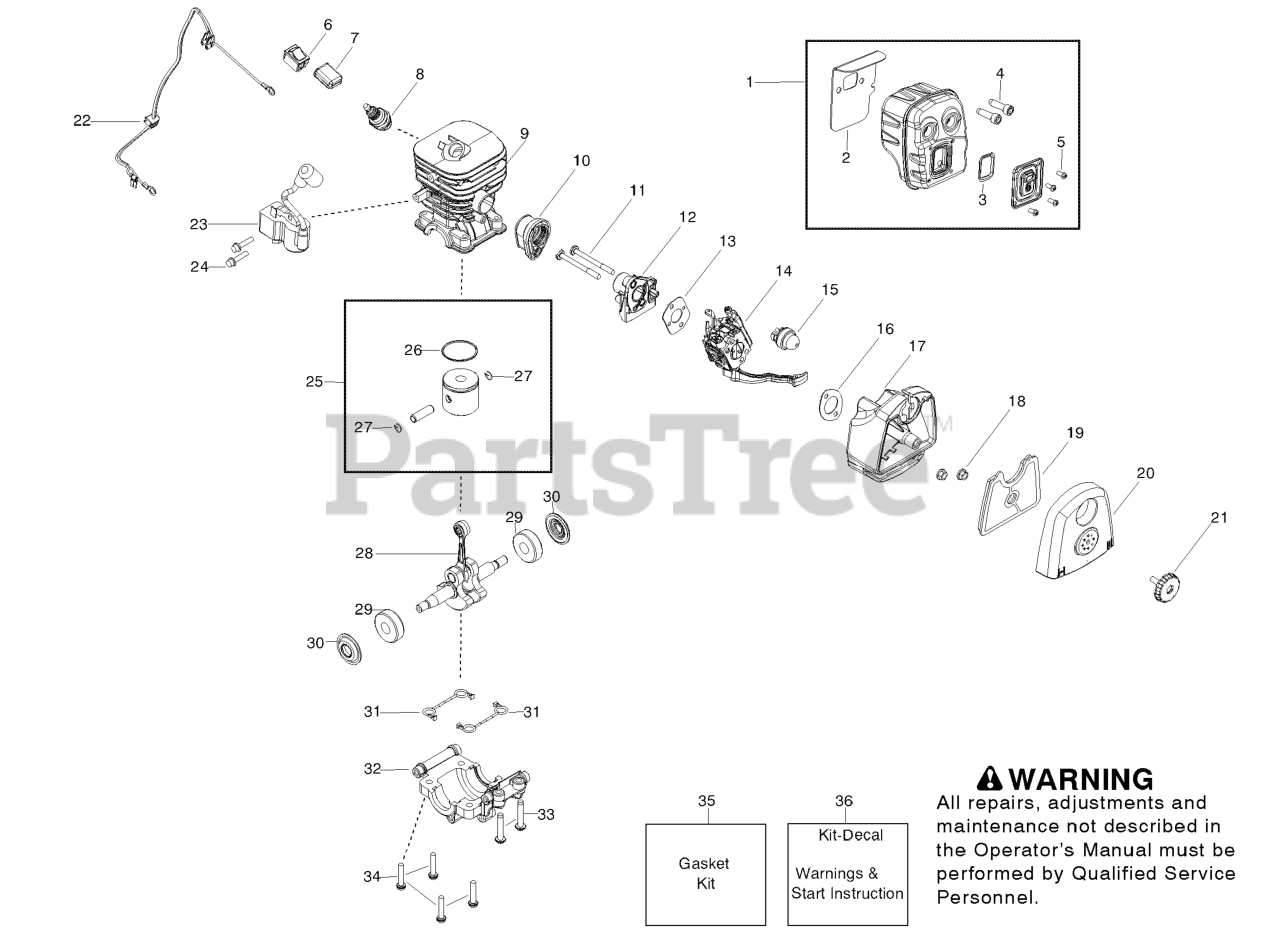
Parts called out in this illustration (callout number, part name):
1	ASSY, MUFFLER
2	GASKET
3	KIT, SPARK SCREEN
4	BOLT MUFFLER
5	SCREW-6-19X5/16PLAST PA
6	KIT SWITCH
7	PROTECTOR, SWITCH
8	Accy - Spark Plug
9	CYLINDER -CHROME
10	BOOT, CARB
12	PLATE, CARB
13	GASKET
14	KIT, CARB
15	AIR PURGE
16	GASKET
17	BASE, AIRBOX
19	FILTER, AIR
20	COVER, AIRBOX
21	KNOB ASSY AIRBOX COVER
22	ASSY, LEADWIRE
23	IGNITION MODULE
24	SCREW M4 X .70 TT 16MM
25	KIT - PISTON
26	RING PISTON
27	WRIST PIN RET.
28	KIT, CRANKSHAFT
29	BEARING RADIAL BALL (6201)
30	CRANKSHAFT SEAL
31	GASKET
32	CAP - BEARING
34	SCREW-M5-0.8 X 25MM(TAP)
35	GASKET
36	KIT, DECAL
